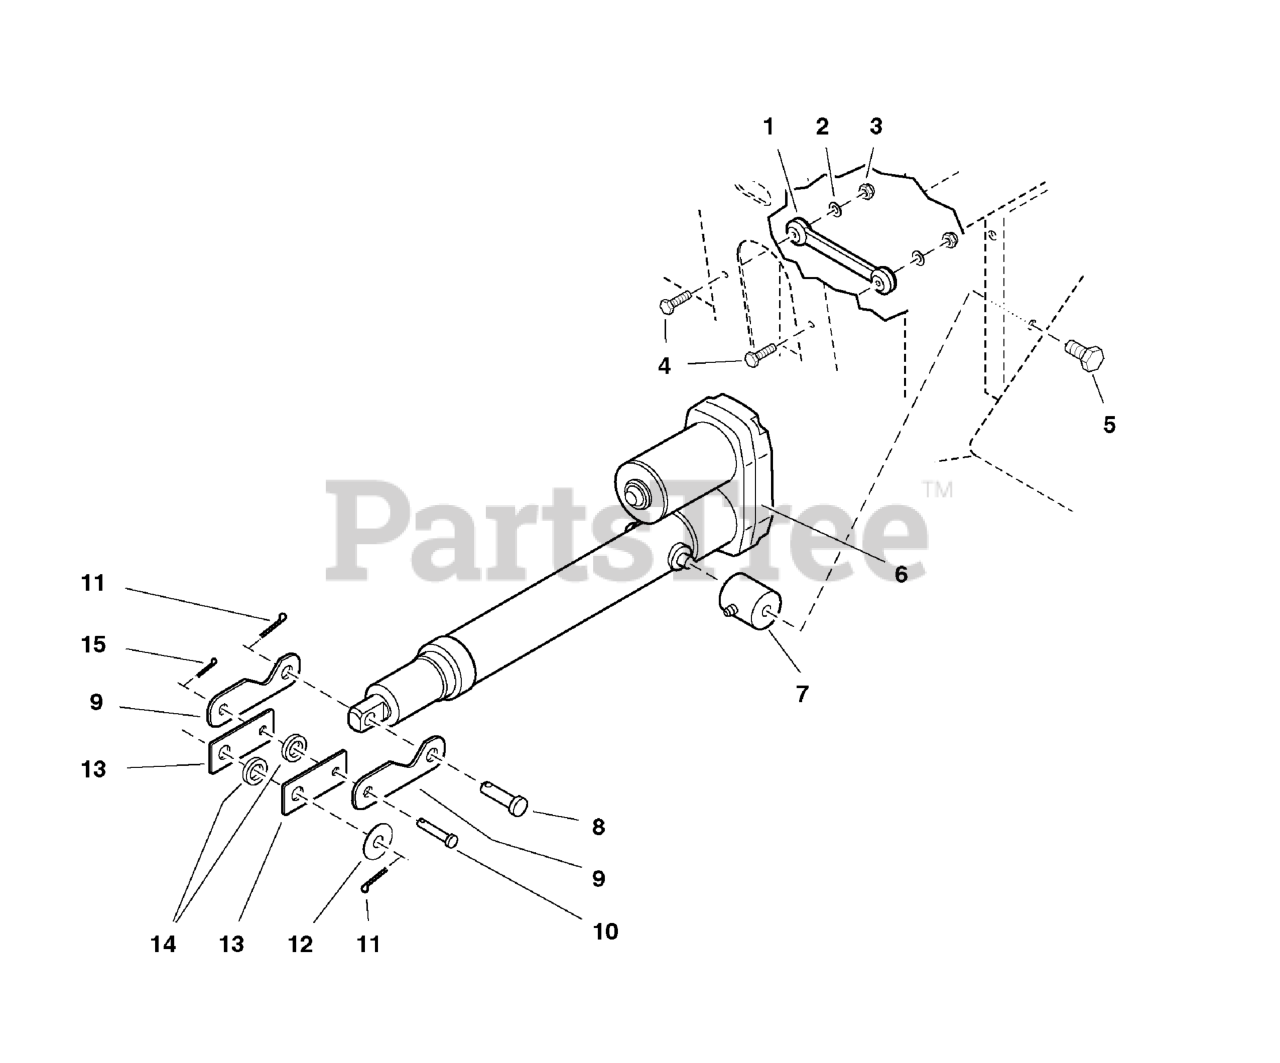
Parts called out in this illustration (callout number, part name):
1	RUBBER STRAP
2	WASHER, 1/4 SAE
3	NUT, 1/4-20 HEX NYLON LOCK
4	BOLT, 1/4-20 X 1" GD5 CZ
5	BOLT, 3/8-16 X 1" GD5 CZ
6	ELECTRIC ACTUATOR
7	ACTUATOR MOUNT
8	PIN, Clevis
9	ACTUATOR LINK, Lower
10	CLEVIS PIN, 3/8 x 1
11	PIN, COTTER, 1/8 X 1-1/4
12	WASHER, 5/8" SAE
13	ACTUATOR LINK, Upper
14	SPACER, .63 x 1.06 x .23
15	PIN, 3/32 X 0.750, COT, ZINC/CLEAR
